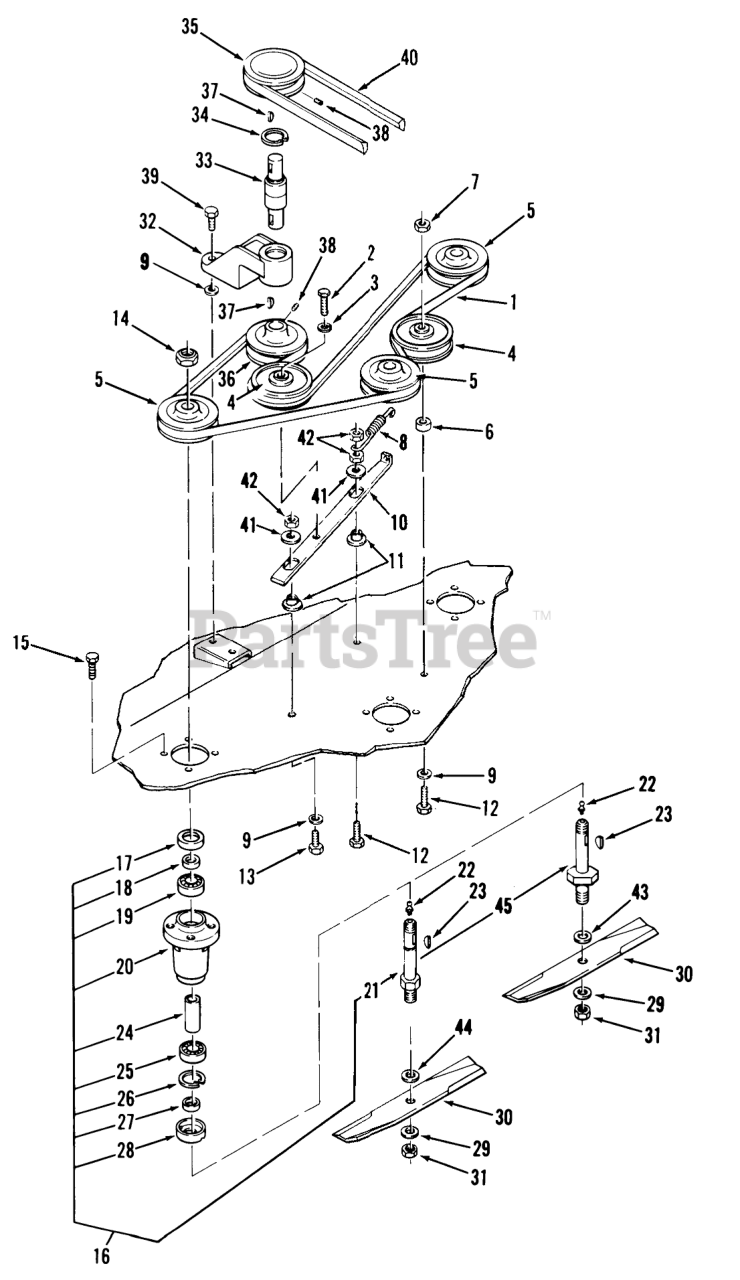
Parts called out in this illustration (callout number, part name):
1	BELT-V
2	BOLT HEX SPECIAL
3	LOCKWASHER
4	Idler Pulley
5	PULLEY-BLADE DRIVE
6	SPACER
7	Nut
8	SPRING-EXTENSION
9	WASHER
10	BAR-IDLER SUPPORT
11	SPACER-BUSHING
12	Bolt
13	Bolt
14	Nut
15	Bolt
16	Spindle Assembly
18	SPACER-SEAL
19	BEARING-BALL
20	HOUSING-SPINDLE
21	SPINDLE SHAFT ASM
22	Grease Fitting
23	Hi-Pro Key 3/16 x 5/8
24	SPACER
25	BEARING-BALL
26	Ring-Snap
27	SPACER-BLADE
28	CUP-SPINDLE
29	SpeciaI Washer
30	S/A BLADE KIT
31	Nut
32	HOUSING DRIVE BRG R
33	BEARING-INT SHAFT
34	Snap Ring
35	PULLEY
36	Pulley
37	KEY-WOODRUFF
38	Set Screw
39	Bolt
40	V-BELT
41	WASHER
42	NUT
43	SpeciaI Washer
44	Washer
45	Spindle Shaft
